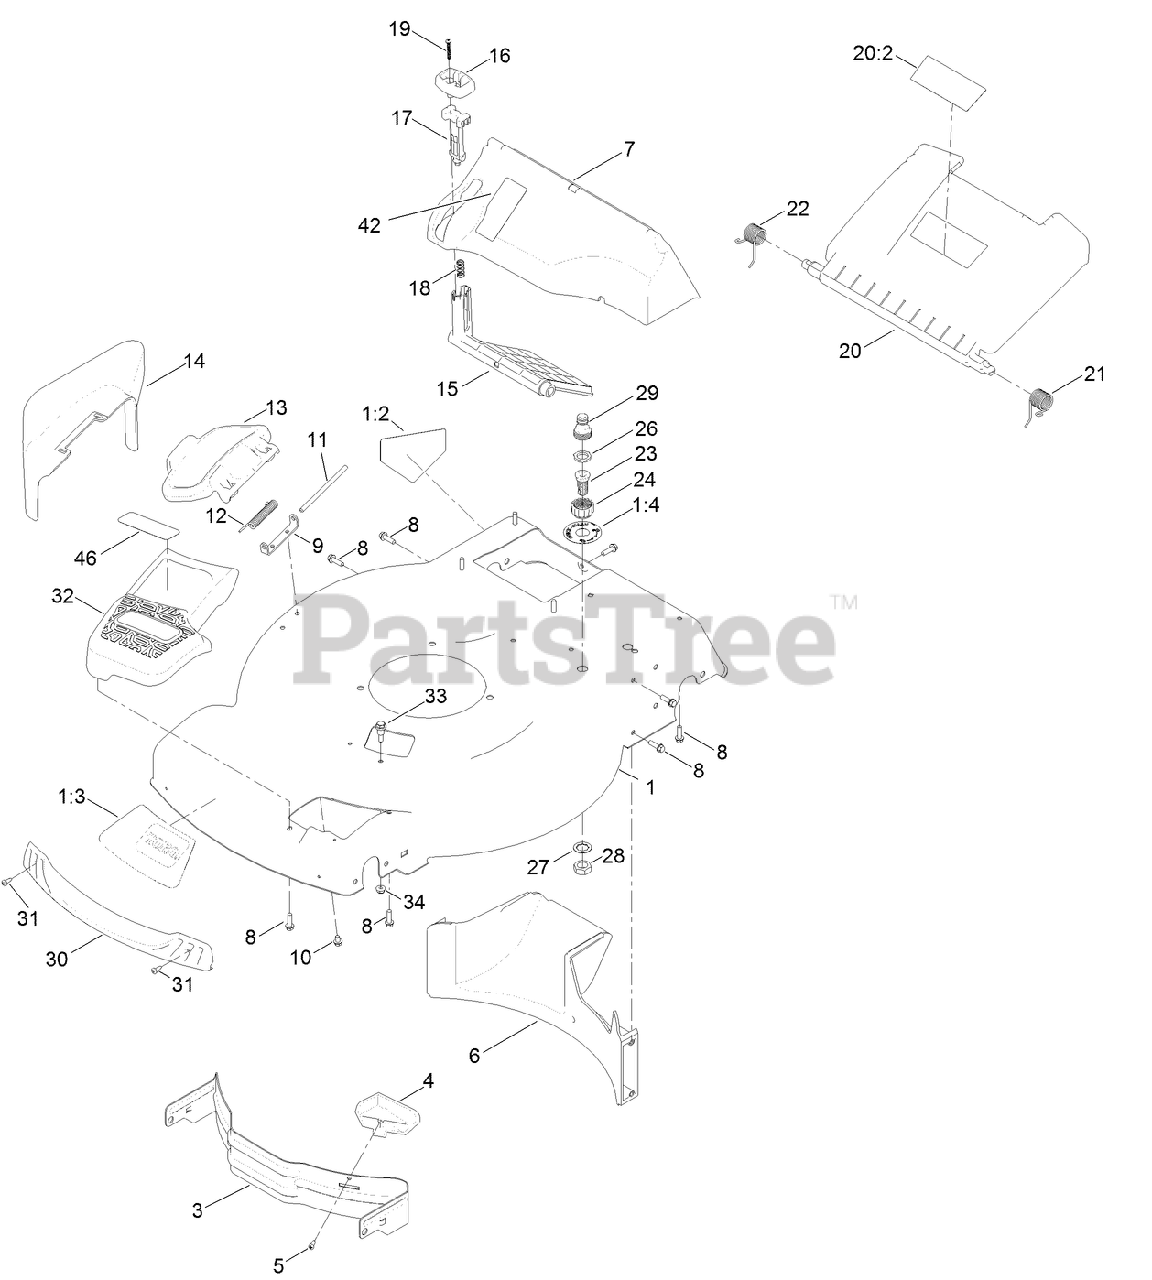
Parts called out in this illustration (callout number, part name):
1	HOUSING ASM
1:2	DECAL-DANGER
1:3	DECAL-DECK
1:4	DECAL-PORT, WASHOUT
3	BAFFLE-FRONT
4	KICKER-FRONT
5	SCREW-PPH
6	BAFFLE-REAR
7	CHUTE-RECYCLE
8	SCREW-HWH
9	BRACKET-COVER
10	SCREW-HWH
12	SPRING-TORSION
13	DEFLECTOR-SIDE
14	CHUTE-DISCHARGE, SIDE
15	DEFLECTOR-RECYCLE
16	KNOB-RECYCLE
17	LATCH-RECYCLE
18	SPRING-COMPRESSION
19	SCREW-PPH
20:2	DECAL-WARNING
21	SPRING-TORSION
22	SPRING-TORSION
23	PORT-WASHOUT
24	COUPLING-HOSE, WASHOUT PORT
26	WASHER-SEAL, WASHOUT PORT
27	WASHER-LOCK
28	NUT-JAM
29	ADAPTER-CONNECT, QUICK
30	BUMPER
31	SCREW-FORMING, THREAD
32	COVER-BELT, FRONT
33	BOLT-SHOULDER
34	NUT-LOCK, NI
46	DECAL-COVER
